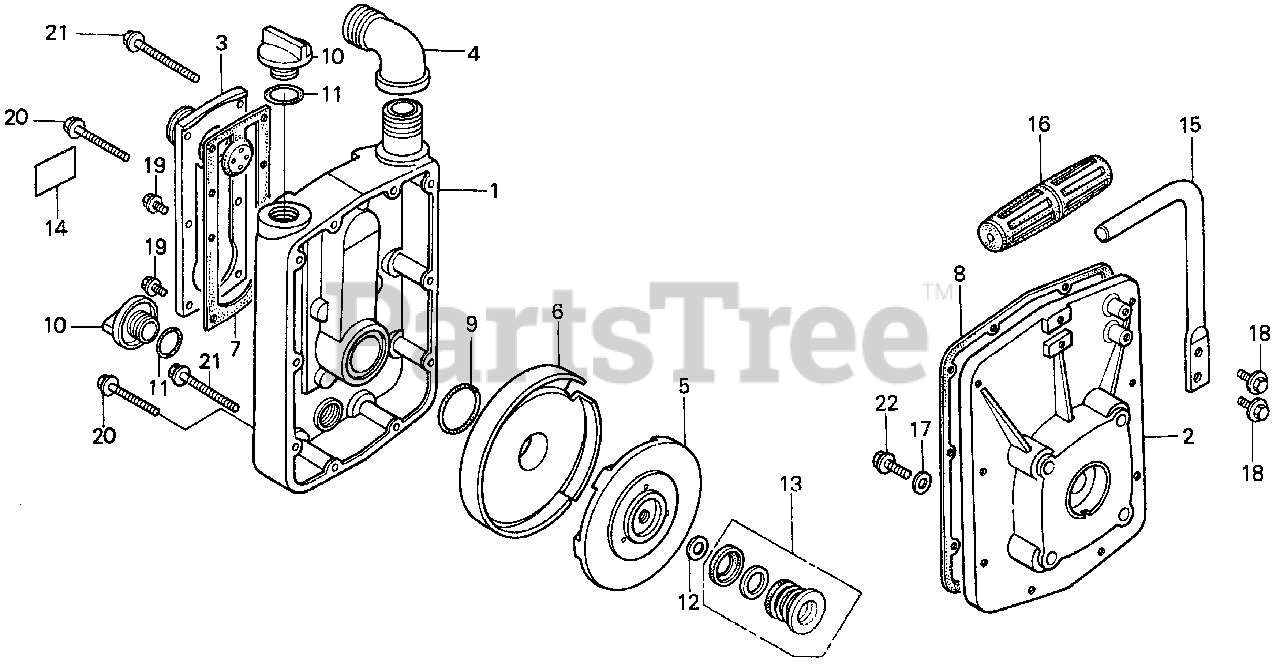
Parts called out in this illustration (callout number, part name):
2	PLATE, END (NOT AVAILABLE)
3	PLATE, SUCTION
3	PLATE, SUCTION (NPTF)
4	OUTLET (NOT AVAILABLE)
5	IMPELLER
6	CASE, VOLUTE
7	GASKET, SUCTION
8	GASKET, END PLATE
9	RING A, SEAL
10	CAP, FILLER
11	RING, SEAL (B)
12	SHIM, ADJUSTER
13	SEAL ASSY., MECHANICAL
15	HANDLE (NOT AVAILABLE)
16	GRIP, HANDLE (NOT AVAILABLE)
17	WASHER (8MM)
18	BOLT, FLANGE (6X12)
19	BOLT, FLANGE (6X16)
20	BOLT, FLANGE (6X45)
21	BOLT, FLANGE (6X65)
22	BOLT, FLANGE (8X25)
